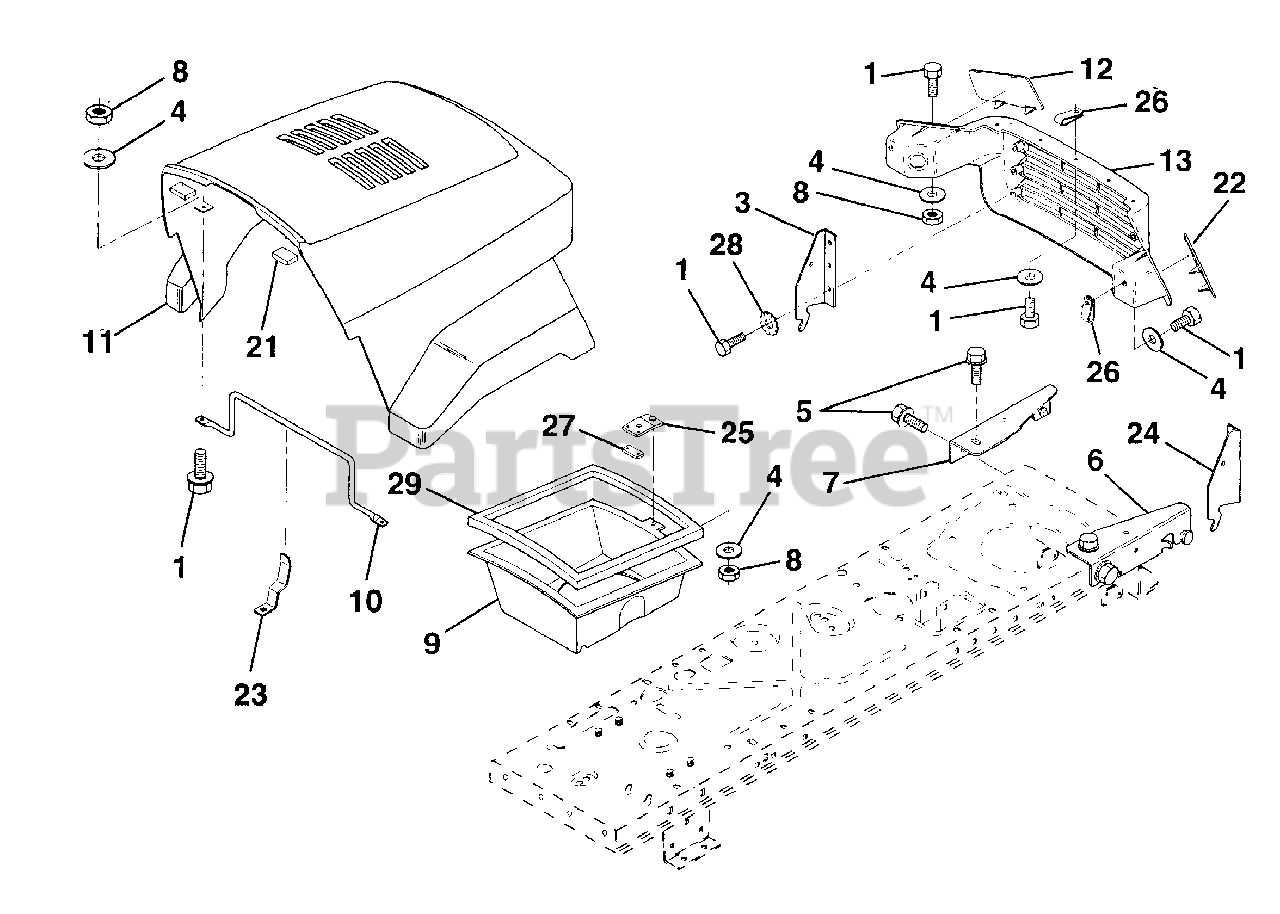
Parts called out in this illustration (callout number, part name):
1	Bolt Fin Hex 1 /4-20 x 5/8
3	Bracket Pivot Hood LH
4	Washer, Flat 1/4
5	Screw Thdrol 5/16-28 x 3/4
6	Bracket Asm. Pivot Hood RH
7	Bracket Asm. Pivot Hood LH
8	Nut Fin Hex 1/4-20
9	Duct Air Hood
10	Brace Hood
13	Grille
21	Bumper Hood
23	Latch Hood
24	Bracket Pivot Hood RH
25	Clip Asm. Duct Air
26	Clip Tinnerman
27	Clip Tinnerman
28	Washer Lock Ext. Tooth
29	Strip Foam
